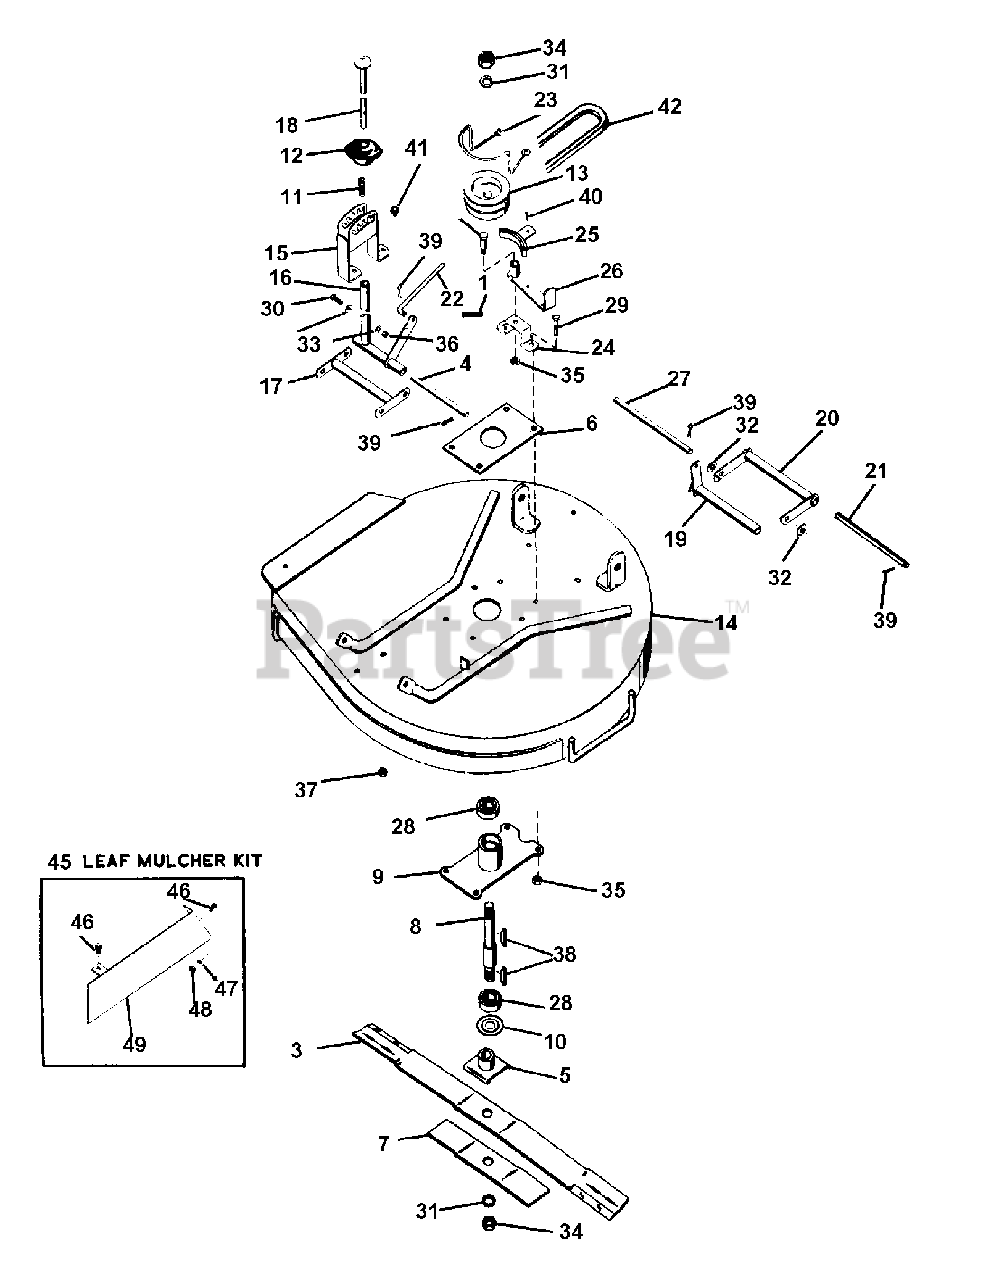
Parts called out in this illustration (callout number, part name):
1	SPRING
2	SHOULDER BOLT .50 X 1.75
3	MOWER BLADE
4	ADAPTER PIN
5	BLADE RETAINER
7	BLADE STIFFNER
8	MOWER SPINDLE
9	SPINDLE HOUSING
10	BEARING SLINGER
11	SPRING
12	SHIFT BALL
13	MOWER SHEAVE
14	MOWER PAN
15	MOWER HGHT QUAD
17	FLOATING LINK
18	HGHT CNTL PLNGR
19	REAR RAISING BRACKET
20	REAR FLOAT BRACKET
21	REAR BRACKET PIN
22	HGHT LINK ROD
23	MOWER BELT FINGER
24	BLADE BRAKE SUPPORT
25	BLADE BRAKE
26	BLADE BRAKE ARM
27	HANGER PIN
28	BRG-BALL .751X1.78X.61
29	BLT-HEX .38-16X1.00 PL
30	BLT-HEX .44-14X1.25 PL GR2
31	WSHR-LK .750X.188 MED PL
32	WSHR-FL-STL .531X1.062X.095 PL
33	WSHR-FL-STL .531X1.062X.095 PL
34	NUT-JAM .625-11
35	NUT-LK-CTR .375-16 GR A PL
36	NUT-LK-CTR .250-20 PL
37	NUT-LK .312-18 GR A PL
38	KEY-WDRF .188X.75X.313 SAE 9
39	PIN-COTR .12X1.0 PL
40	RVT .25X.50 RH ST
41	BLT-SERHFWH .31-18X.50 PL
42	BELT,5L RAW LAMINATED
45	Leaf Mulcher Kit(Inc. 46,47,48,49)
46	BLT-SERHFWH .31-18X.50 PL
47	WSHR-LK .312X.097 PL HVY
48	NUT-JAM .375-16 PL
49	LEAF MULCHER
